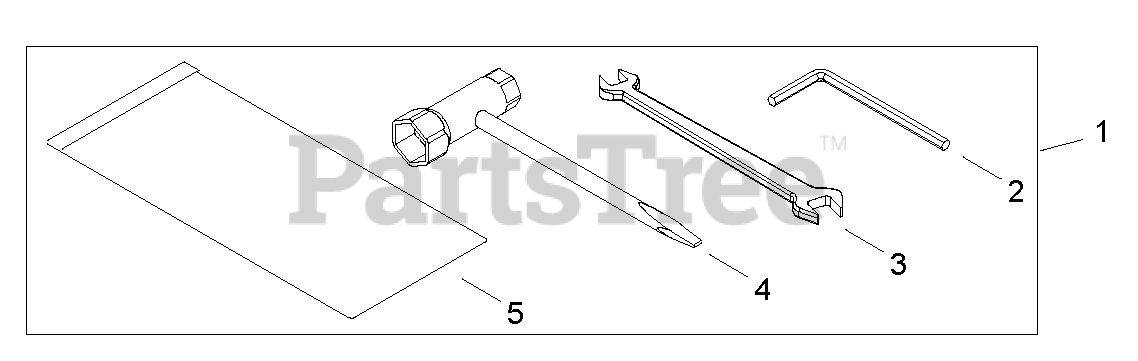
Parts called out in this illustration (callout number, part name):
1	TOOL KIT
2	HEX KEY - 4mm
3	SPANNER - 8X10mm
4	T-WRENCH - 13X16mm
5	BAG, TOOL
